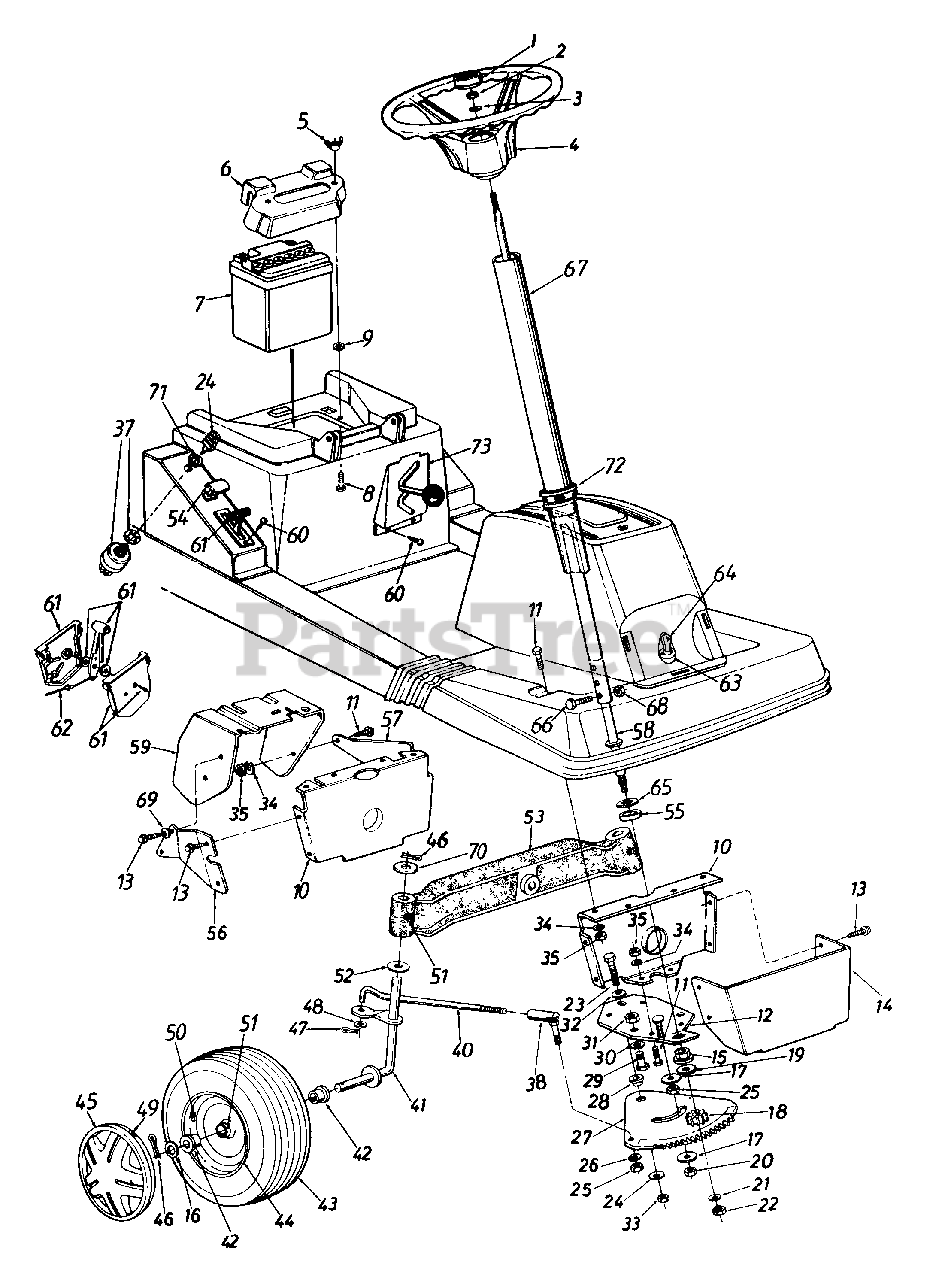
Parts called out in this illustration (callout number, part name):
1	Steering Wheel Cap
2	Hex L-Nut 5/16-24 Thd.
3	Bell-Wash. .345" I.D. x .88" O.D.
4	Steering Wheel Ass'y.
5	Wing Nut 1/4-20 Thd. (Nylon)
6	Battery Hold Down Cover
7	12V Battery
8	Hex Bolt 1/4-20 x 1.75" Lg.
9	Push On Retaining Ring
12	Steering Gear Support Brkt. Ass'y.
13	Hex Wash. Hd. AB-Tap Scr. 1/4 x .62" Lg.
16	FI-Wash. .635" I.D. x 1.585"
17	FI-Wash. .385" x 1.37" O.D.
18	Steering Pinion Gear
19	FI-Wash. .510" I.D. x 1.0" O.D.
20	Hex L-Nut 3/8-24 Thd.
21	FI-Wash. .34" I.D. x .68" O.D.
22	Hex Nut 5/16-24 Thd.
23	Hex Bolt 3/8-24 x 1.5" Lg. (Gr. 5)
24	Ignition Key Set
25	Hex Nut 3/8-24 Thd.
26	L-Wash. 3/8" I.D.
27	Steering Gear Segment
28	Shld. Spacer
29	Hex Bolt (Nylon) 1/2-13 x .75" Lg.
30	FI-Wash. .53" I.D. x .93" O.D.
31	Hex Nut 1/2-13 Thd.
32	Bell-Wash..385" I.D. x .88"
34	L-Wash. 5/16" I.D.
35	Hex Nut 5/16-18 Thd.
37	Ignition Switch
38	Ball Joint Ass'y
40	Steering Tie Rod
41	Front Axle Ass'y -- R.H.
42	Wheel Bearing
46	Cotter Pin 1/8" Dia. x 1.25" Lg
47	Cotter Pin 1/8" Dia. x 1.0" Lg.
48	FI-Wash..385" I.D x .87" O.D.
49	Spring Clip
50	Air Valve
51	Grease Fitting
52	Fl-Wash. 76" I.D. x 1.49" O.D.
55	Spacer 985" I D. x 1.25"
61	Throttle Control Box Ass'y.
62	Throttle Control Wire 22" Lg.
63	Headlight Socket
64	Lamp
65	FI-Wash..64" I.D. x 1.24"
66	Hex Bolt 1/4-20 x 1.25" Lg
67	Steering Shaft Ass'y
68	Hex L-Nut 1/4-20 Thd
69	Bell-Wash..345" I.D. x.88" O.D.
70	FI-Wash..75" I.D. x 1.5" O.D.
71	Ignition Switch Nut
72	Steering Cover Brg.
73	FNR Index Brkt.
